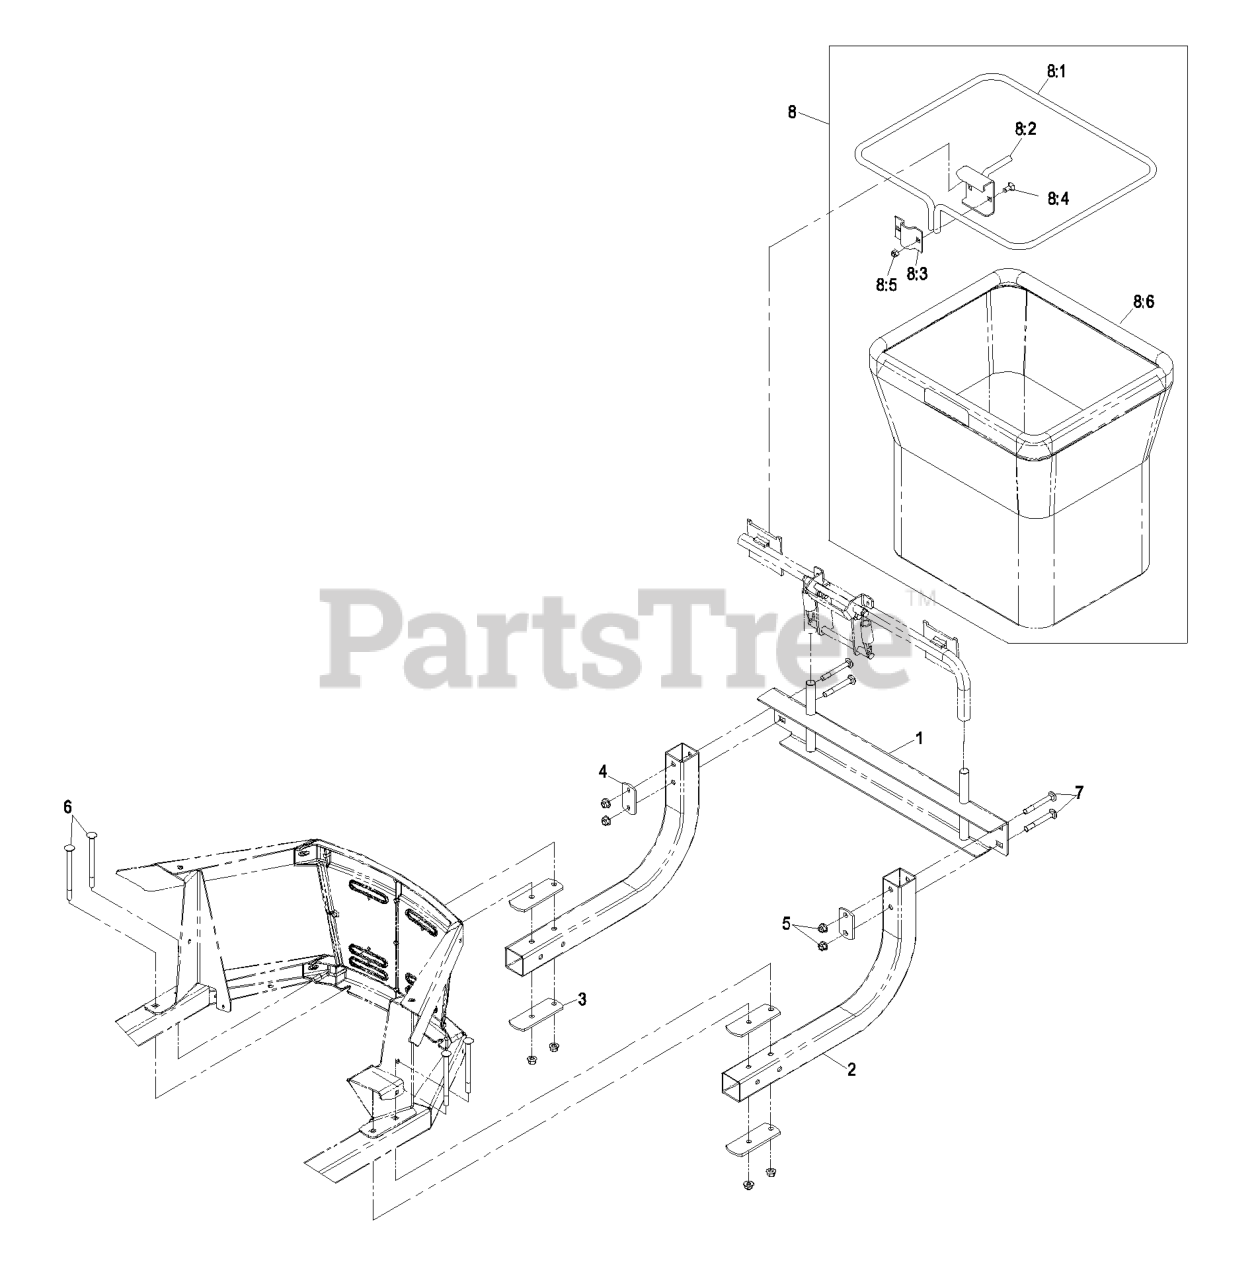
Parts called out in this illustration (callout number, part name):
1	BAGGER HITCH ASM
2	TUBE-HITCH, BAGGER
3	PLATE-STIFFENER
4	PLATE-STIFFENER
5	NUT-HF, NI
6	BOLT-CARR
7	SCREW-CARR
8	ASM,BAG
8:1	FRAME-BAG
8:4	BOLT-CARR
8:5	NUT-LOCK, NI
8:6	BAG,20 IN. DEPTH
